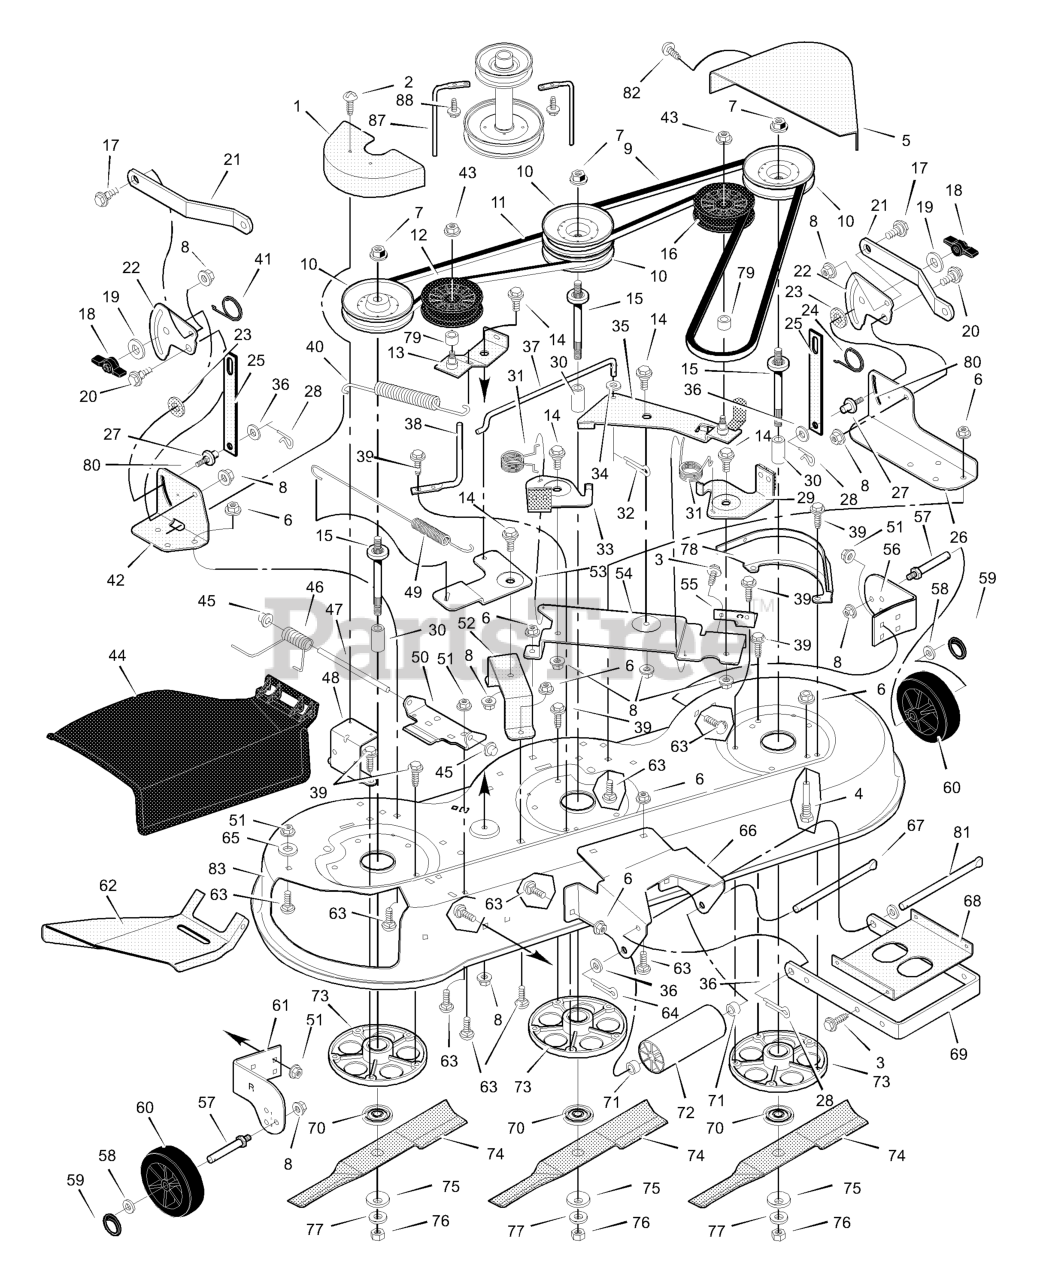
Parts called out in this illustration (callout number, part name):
1	Cover, Right Pulley
2	Screw
4	Guide, Belt
5	Cover, Left Pulley
6	Nut, Hex
7	Nut, Flange
8	Nut, Flange
9	Belt, Primary
10	Pulley
11	Belt, Secondary
12	Pulley, Idler
13	Arm, Idler
14	Bolt, Shoulder
15	Shaft, Splined
16	Pulley, Idler
17	Bolt, Shoulder
18	Knob
20	Bolt, Shoulder
21	Bracket, Rear Suspension
22	Plate, Suspension
23	Pad, Friction
25	Link, Lift
26	Bracket, Left Lift
27	Pin, Hanger
28	Pin, Hair
29	Brake Assembly, Left
32	Pin, Cotter
33	Brake Assembly, Right
34	Washer
35	Idler, Arm
37	Link, Bell Crank
38	Guide, Belt
39	Screw
40	Spring, Extension
41	Spring, Torsion
42	Bracket, Suspension
43	Nut
44	Deflector, Chute
45	Push On Cap
46	Spring, Torsion
47	Rod, Deflector
48	Bracket, Cover
49	Spring, Extension
50	Bracket, Hinge
51	Nut, Flange
52	Bracket, Bell Crank
53	Crank, Bell
54	Plate, Brake Arm
55	Bracket, Brake Plate
56	Bracket, Left Gauge Wheel
57	BOLT, Gauge Wheel
59	Ring, Locking
60	Wheel, Gauge
61	Bracket, Right Gauge Wheel
62	Deflector, Inside
63	Bolt, Carriage
64	Pin, Cotter
66	Bracket, Front Deck
67	Rod, Hanger
68	Stiffener
69	Bracket, Suspension
70	Adapter, Blade
73	Housing, Jackshaft
75	Washer, Belleville
78	Bracket, Pulley Cover
81	Rod, Hanger
83	Housing, Blade
87	Guide, Belt
88	Screw
